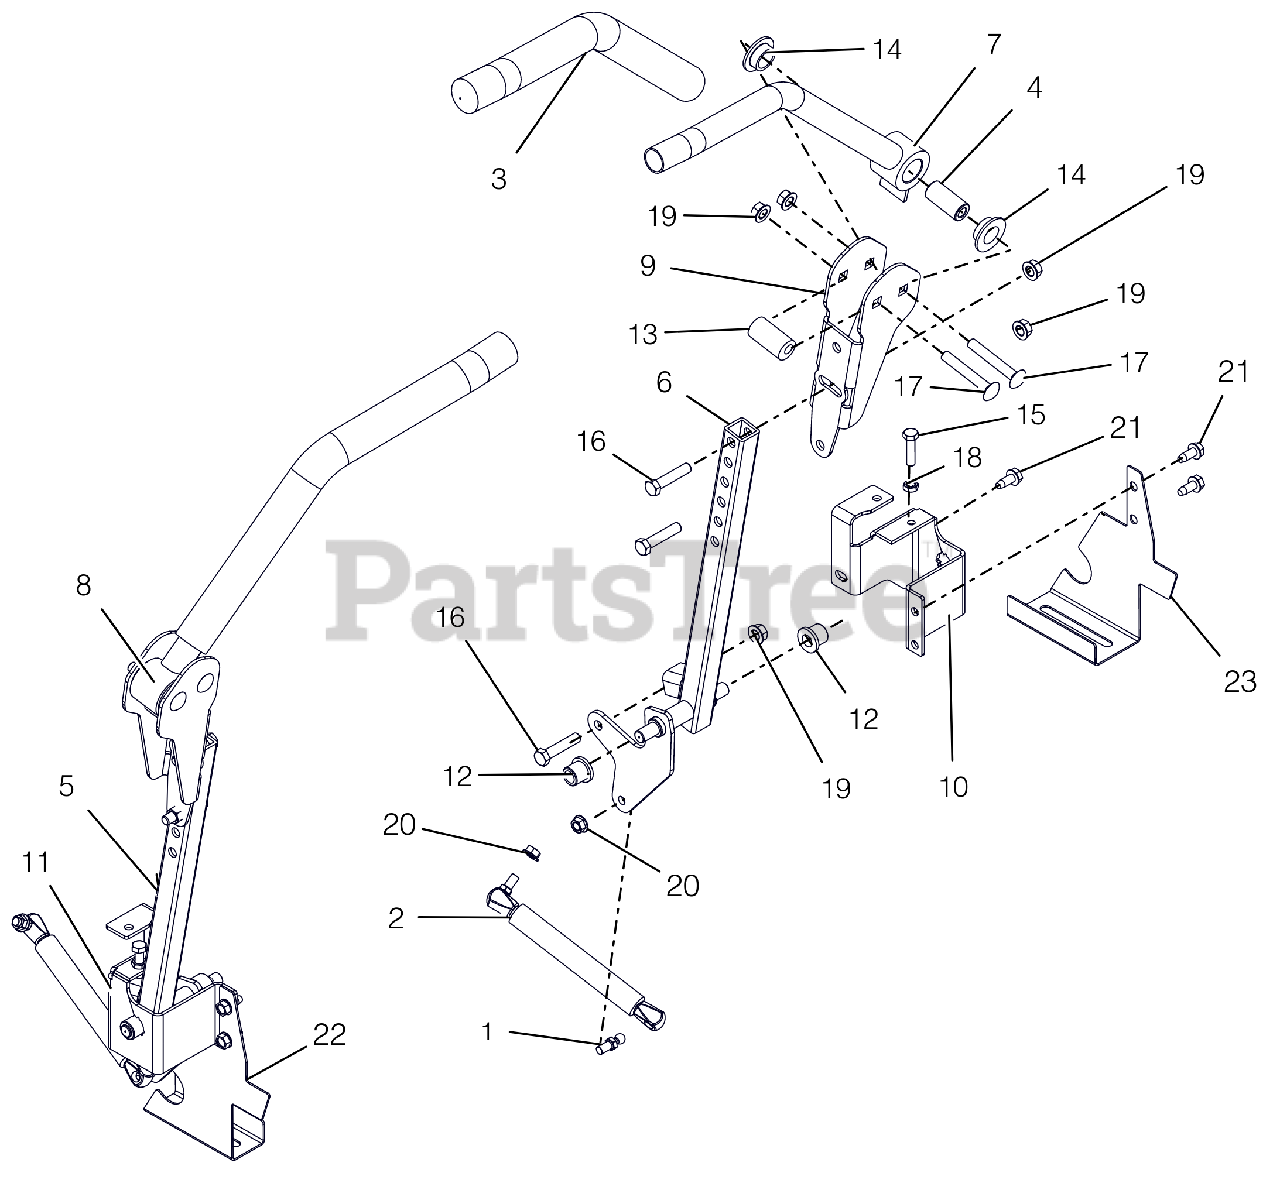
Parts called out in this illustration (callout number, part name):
1	STUD- BALL
2	DAMPER
3	GRIP, HANDLEBAR
4	SPACER, STEERING ARM
5	WLDMT, STEERING RH
6	WLDMT, STEERING LH
7	WLDMT, CONTROL HANDLE- BLK
8	WLDMT, CONTROL HANDLE- BLK
9	ADJ UPPER CONTROL ARM BRKT-BLK
10	BRKT, STEERING ARM MOUNT -LH
11	BRKT, STEERING ARM MOUNT -RH
12	BHSG-FLG .500X.750X.750X.125
13	BSHG, ECCENTRIC.406X.875X1.625
14	BSHG-FLG .762X1.48X.44 NYL
15	@BLT-HEX .31-18X1.25 GR5 YWZC
16	@BLT-HEX .38-16X1.75 GR5 YWZC
17	BLT-RDHDSQSHK, 38-16X2.50 G5YZ
18	NUT- JAM .312-18 YWZC
19	@NUT-LK-TOP-FLG .38-16 YWZC
20	@NUT-LK-TOP-FLG .31-18 YWZC
21	@SCR-TAP .31-18X.75 HWH TR YWZ
22	GUARD, FRAME RAIL BELT RH
23	GUARD, FRAME RAIL BELT LH
